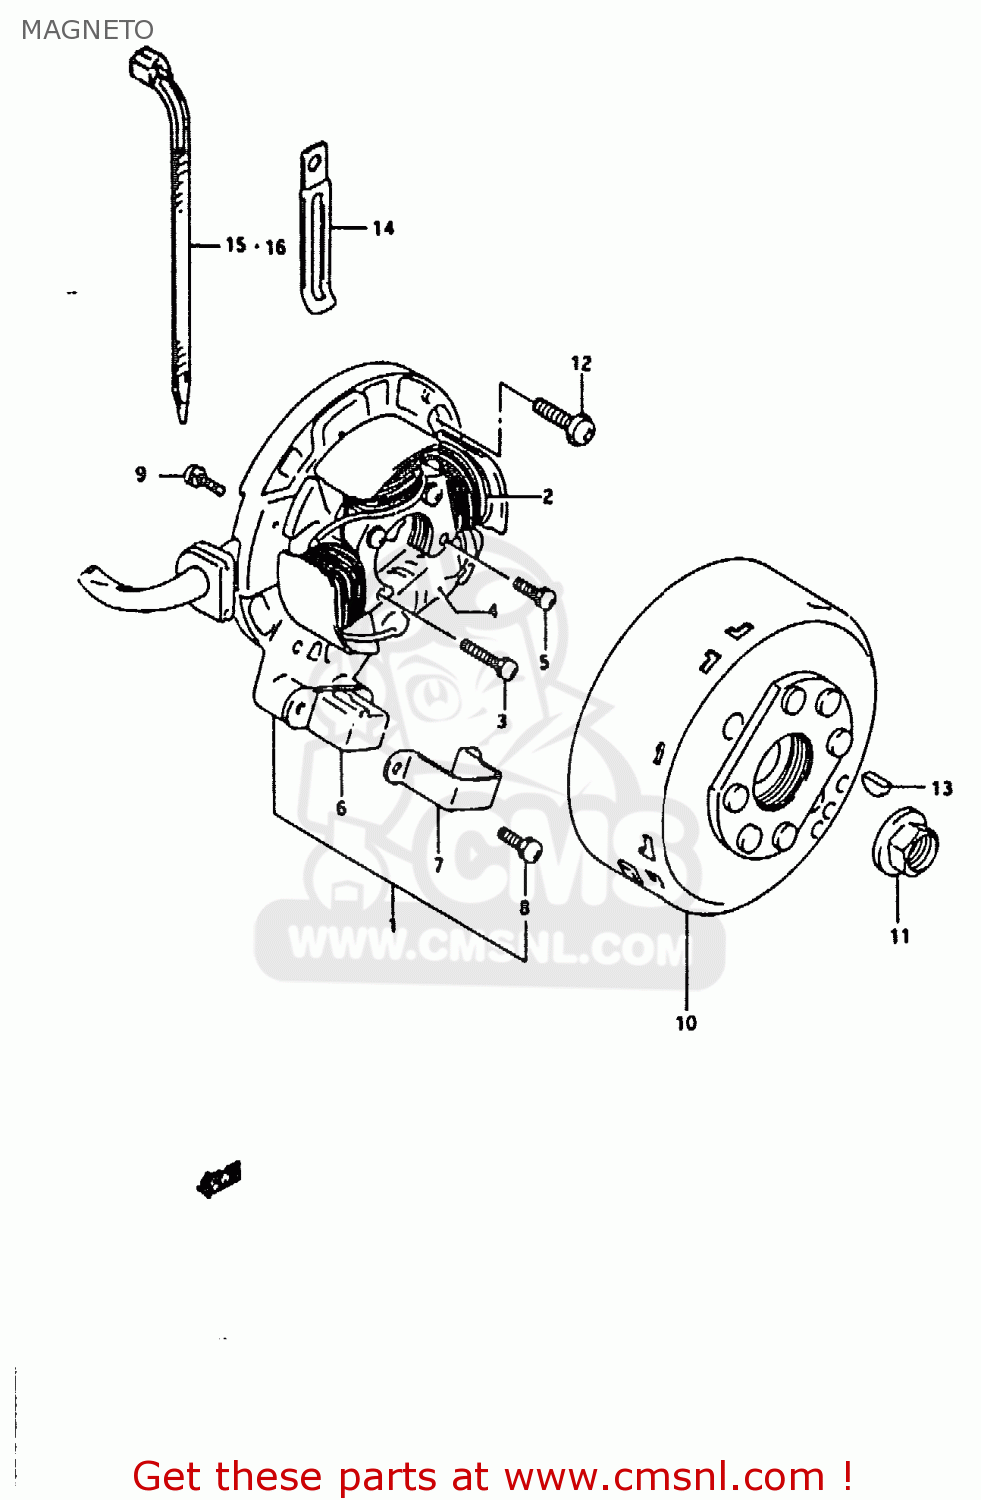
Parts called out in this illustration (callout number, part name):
1	STARTER ASSY
2	COIL,LIGHTING
3	SCREW
4	COIL,PRIMARY
5	SCREW
6	COIL,PULSER
7	HOLDER,PICK UP COIL
8	SCREW
9	SCREW
10	ROTOR ASSY
11	NUT
12	SCREW
13	KEY
14	CLAMP
15	CLAMP(L:125)
16	CLAMP(L:235)
